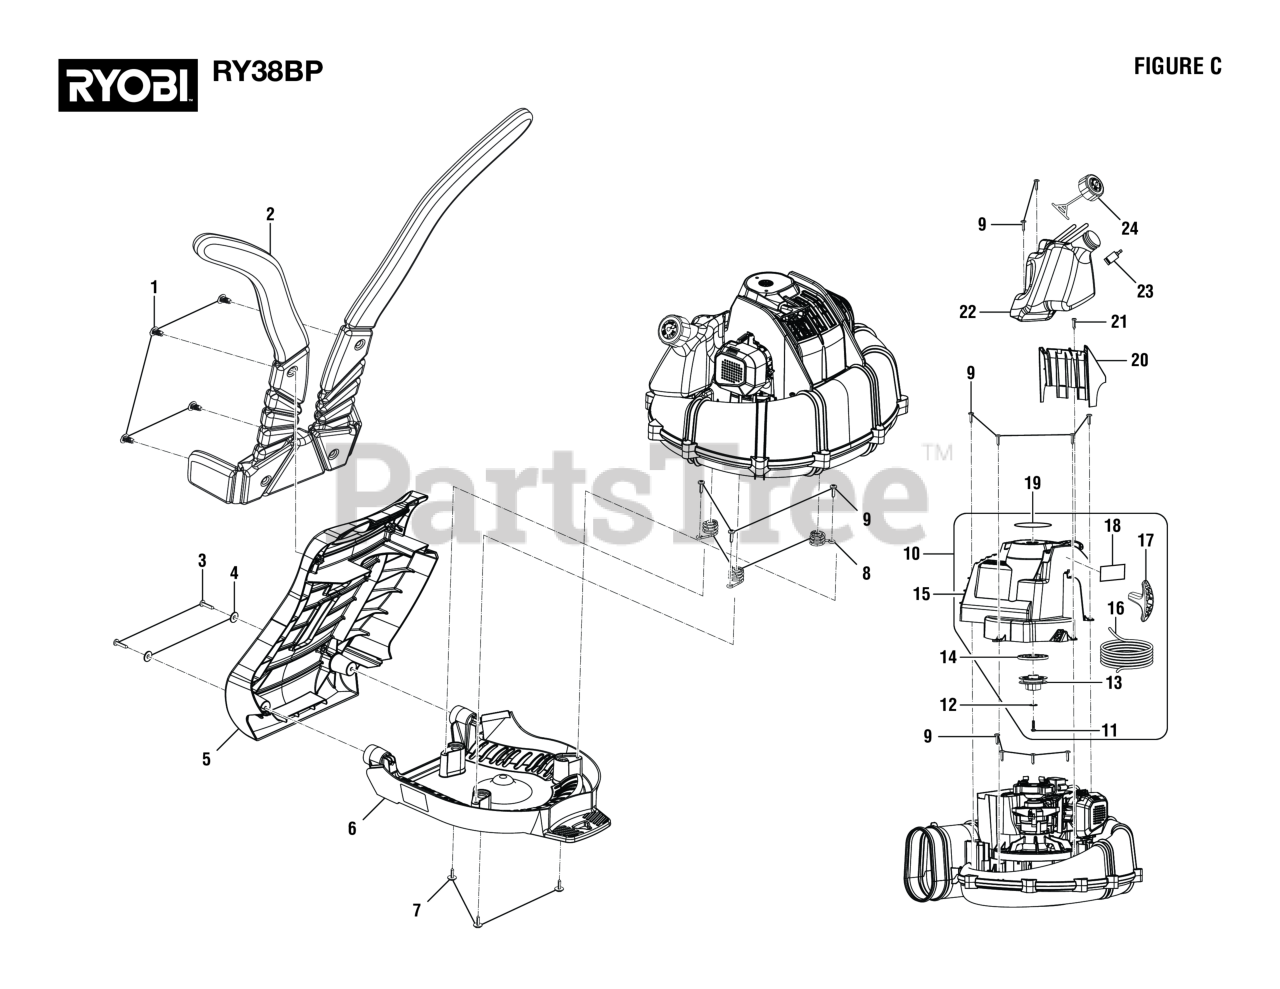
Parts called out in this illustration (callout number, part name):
1	Harness Snap Fastener
3	SCREW (10-14 X 1 in.)
4	Washer (OD16 x ID6.8 x 1.5t)
5	Upper Frame
6	Lower Frame
7	Screw (10-14 x 16 mm)
9	Screw (10-14 x 19 mm, T25 Torx Truss Pan Hd. T.F.)
10	Engine Housing and Starter Assembly
11	Screw (M5 x 14 mm, T25 Torx Pan Hd.)
12	Washer (16OD x 5.3ID x 1.0t)
13	Starter Pulley
14	SPRING & CONTAINER
15	Engine Housing w/Labels
16	STARTER ROPE 42 (PKG)
17	Pulley Handle
18	Mix Ratio Label
19	Logo Label
20	Spark Plug Cover
21	Screw (#10-14 x 3/4 in, T25 Torx Pan Hd. T.F.)
22	Fuel Tank Assembly w/Fuel Lines
23	Fuel Filter
24	Fuel Cap Assembly (Inc. Tether)
